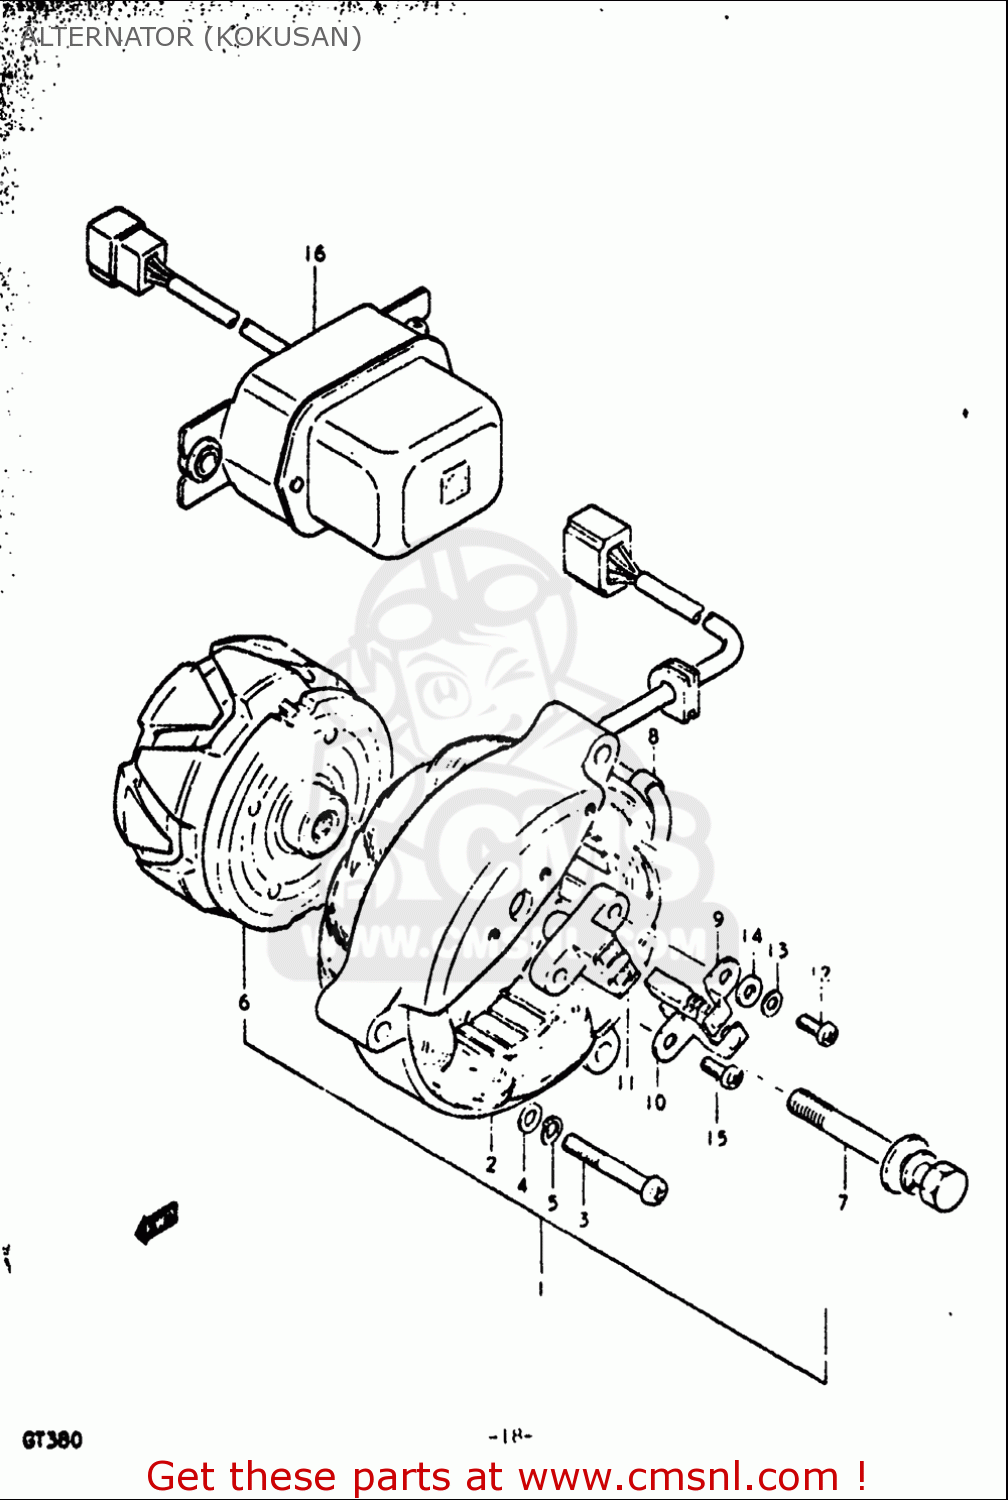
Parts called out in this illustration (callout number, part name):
4	WASHER
5	WASHER,LOCK
7	BOLT
9	BRUSH
10	BRUSH
12	SCREW 4X16
13	WASHER
15	SCREW
